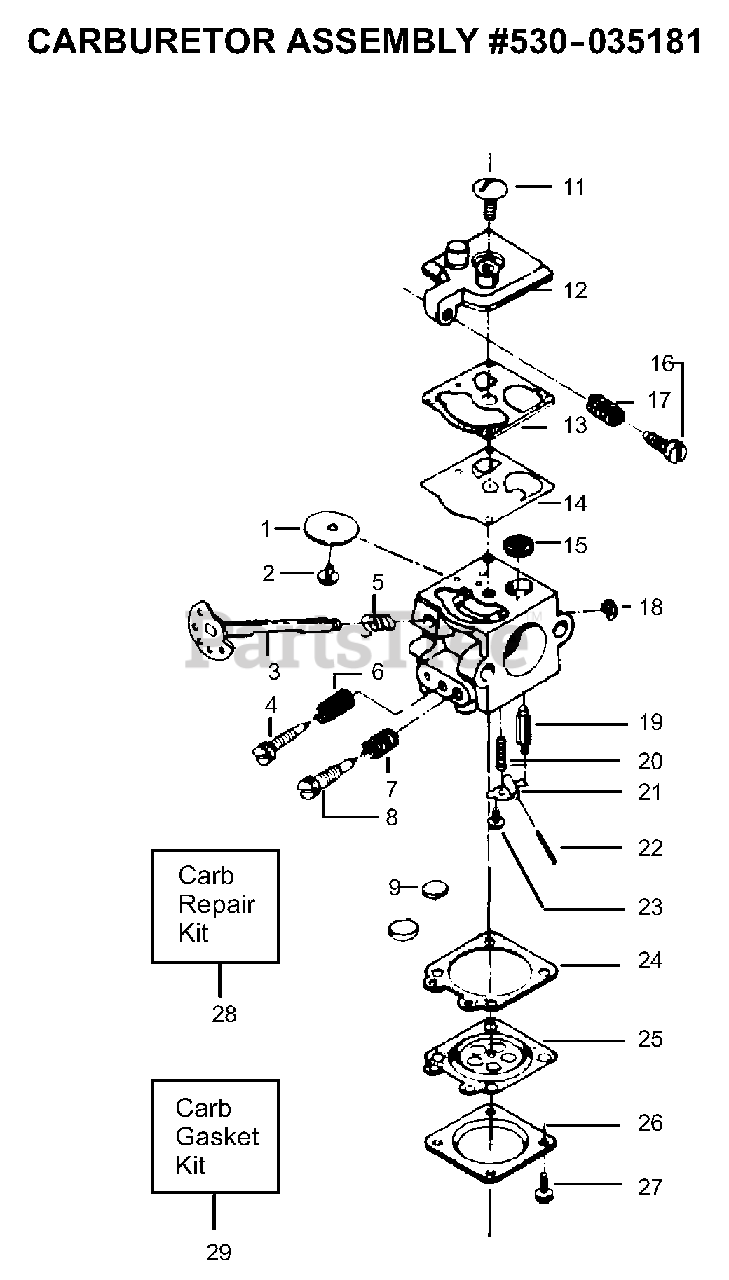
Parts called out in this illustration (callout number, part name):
1	Throttle Valve
2	Throttle Valve Screw
3	Throttle Shaft Ass'y.
4	Low Speed Mixture Needle
5	Throttle Return Spring
6	Low Speed Mixture Needle Spring
7	High Speed Mixture Needle Spring
8	High Speed Mixture Needle
9	Plug-5/16 Dia. Welch
11	Pump Cover Screw
12	Fuel Pump Cover
13	Fuel Pump Gasket
14	Fuel Pump Diaphragm
15	Fuel Inlet Screen
16	Idle Speed Adjusting Screw
17	Idle Speed Adjusting Screw Spring
18	Throttle Retainer Ring
19	Inlet Needle Valve
20	Metering Lever Spring
21	Metering Lever
22	Metering Lever Pin
23	Metering Lever Pin Screw
24	Metering Diaphragm Gasket
25	Metering Diaphragm
26	Metering Diaphragm Cover
27	Metering Cover Screw Ass'y.
28	Carb. Repair Kit
29	Carb. Gasket/Diaphragm
530035181	Carburetor Assembly
